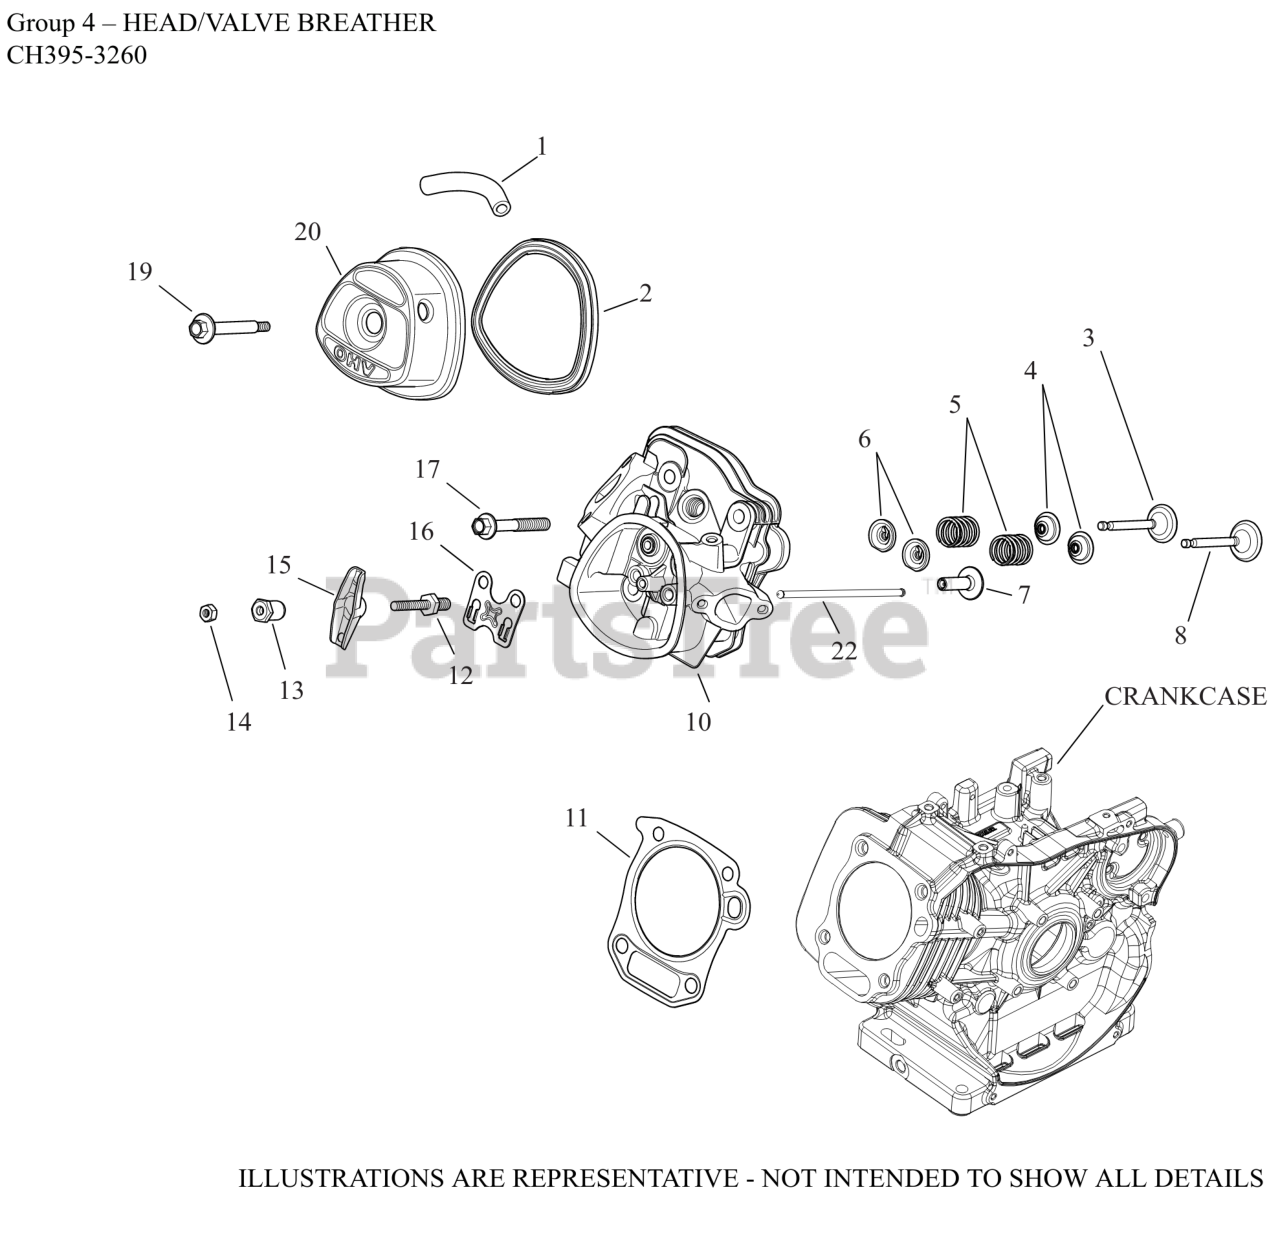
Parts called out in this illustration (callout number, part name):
1	TUBE, BREATHER
2	GASKET, VALVE COVER
3	VALVE, EXHAUST
4	SEAL, VALVE STEM
5	SPRING, VALVE
6	RETAINER, VALVE SPRING
7	LIFTER, VALVE
8	VALVE, INTAKE
10	KIT, HEAD AND VALVE TRAIN
11	KIT, HEAD GASKET
12	STUD, ROCKER ARM-USE 14 072 22-S
13	PIVOT, ROCKER ARM
14	NUT, HEX JAM
15	ARM, ROCKER
16	PLATE, PUSHROD GUIDE
17	SCREW, HEX FLANGE CYLINDER HEAD
19	SCREW, VALVE COVER SEAL ASSY
20	KIT, VALVE COVER ASSEMBLY
22	ROD, PUSH
